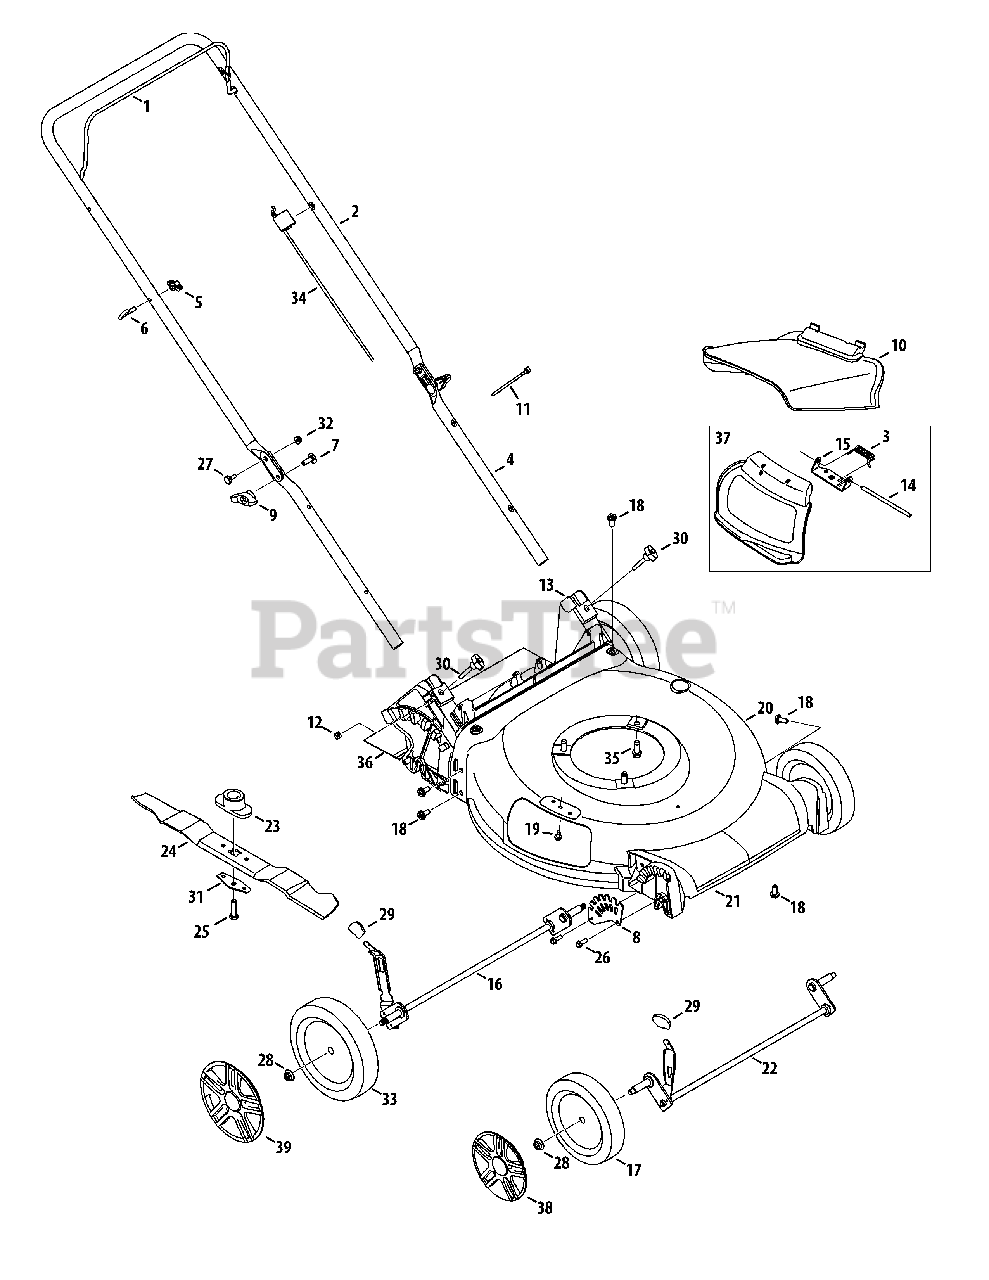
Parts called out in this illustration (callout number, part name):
1	Blade Control
2	Upper Handle, Non-Adjustable
3	Torsion Spring
4	Lower Handle
5	Wing Nut
6	Rope Guide
7	Carriage Screw ,5/16-18
8	Front Height Adjuster Plate
9	Wing Knob
10	Side Chute
11	Cable Tie
12	Nut, Sq., 1/4-20
13	Rear Baffle
14	Hinge Pin
15	Chute Deflector Bracket
16	Rear Axle Assembly
17	Front Wheel, 7 x 1.8, Bar, Gray
18	Screw, 5/16-14 x .750
19	Screw, 1/4-20 x .500
20	Deck , 21"
21	Front Cover
22	Front Axle Assembly
23	Blade Adapter, 139cc
24	Mulching Blade
25	Screw , 3/8-24 x 1.50
26	Screw, 1/4-15 x .750
27	Sldr. Screw, .375 x .126 x 1/4-20
28	Flange Lock Nut, 3/8-16
29	Adjustment Lever Knob
30	Wing Nut
31	Blade Bell Support
32	Nut, Flange Lock, 1/4-20
33	Rear Wheel, 8 x 1.8, Bar, Gray
34	Control Cable, 40.00"
35	TT Sems Screw, 3/8-16 x 1.0
36	Trail shield
37	Hinged Mulch Plug Assembly
38	Hubcap, 7"
39	Hubcap, 8"
